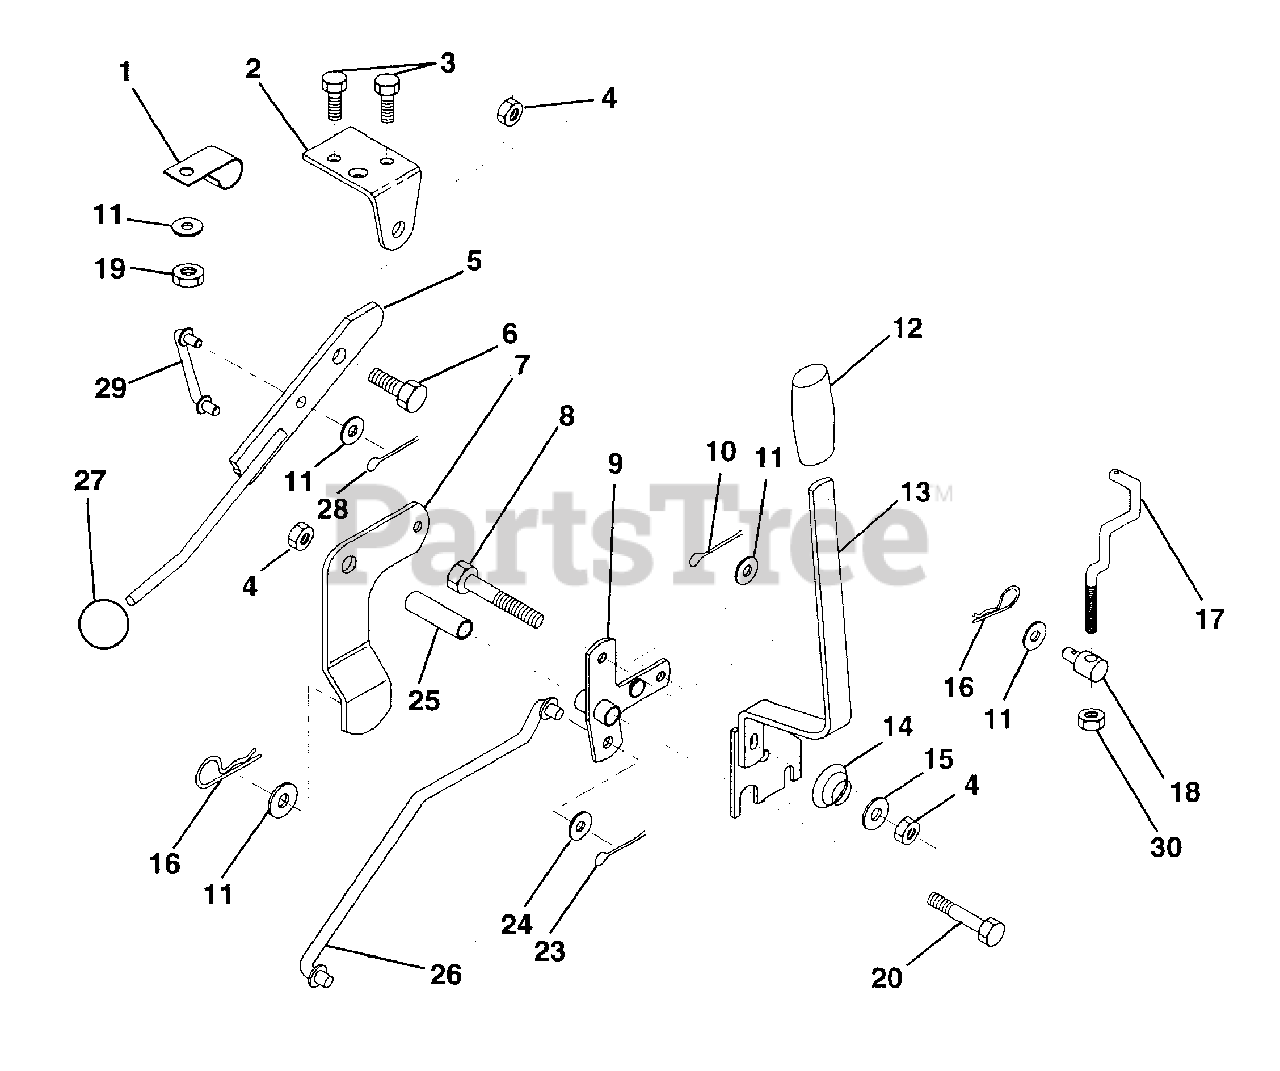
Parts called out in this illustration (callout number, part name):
1	Clip, Insulated
2	Bracket, Mower Clutch
3	Bolt, Fin. Hex 1/4-20 UNC x 1/2 Gr. 5
4	Nut, Crownlock 3/8-16 UNC
5	Assembly, Clutch Lever
6	Bolt, Shoulder
7	Assembly, Mower Clutch Arm
8	Bolt, Hex 3/8-16 UNC x 2-1/4
9	Bellcrank, Asm. Lift
10	Pin, Cotter 1/8 x 3/4
11	Washer 13/32 x 13/16 x 16 Ga.
12	Grip, Handle
13	Assembly, Lift Handle
14	Spring, Compression
15	Washer 13/32 x 3/4 x 12 Ga.
16	Retainer, Spring
17	Link, Front Lift
18	Trunnion, Threaded 3/8-16
19	Nut, Crownlock 1/4-20
20	Bolt, Fin. Hex 3/8-16 U N C x 2-3/4
23	Pin, Cotter 1/8 x 1
24	Washer 17/32 x 1 x 16 Ga.
25	Tube, Spacer
26	Rod, Mower Lift
28	Pin, Cotter 3/32 x 3/4
29	Link, Mower Clutch
30	Nut Hex Jam 3/8-16 Unc
